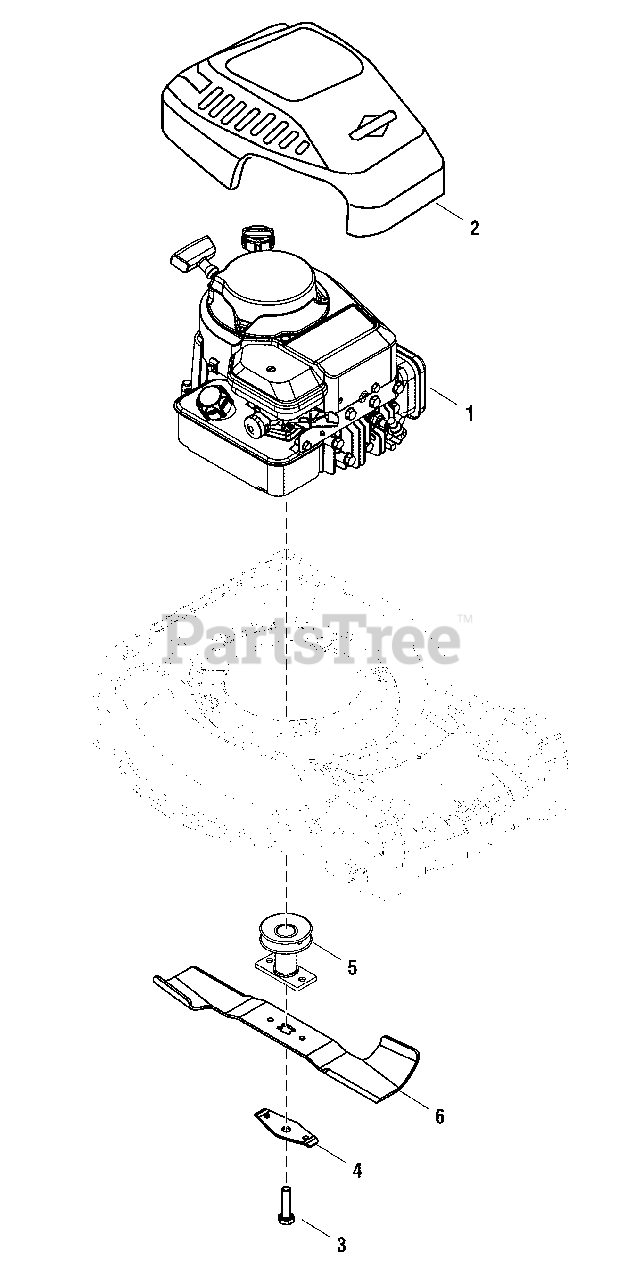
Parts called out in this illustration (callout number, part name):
1	* ENGINE, Briggs & Stratton, Mod. 09P702-0103-H1
3	SCREW Hex, 3/8-24 x 1-1/2
4	SUPPORT, Blade Bell
5	BLADE ADAPTER
